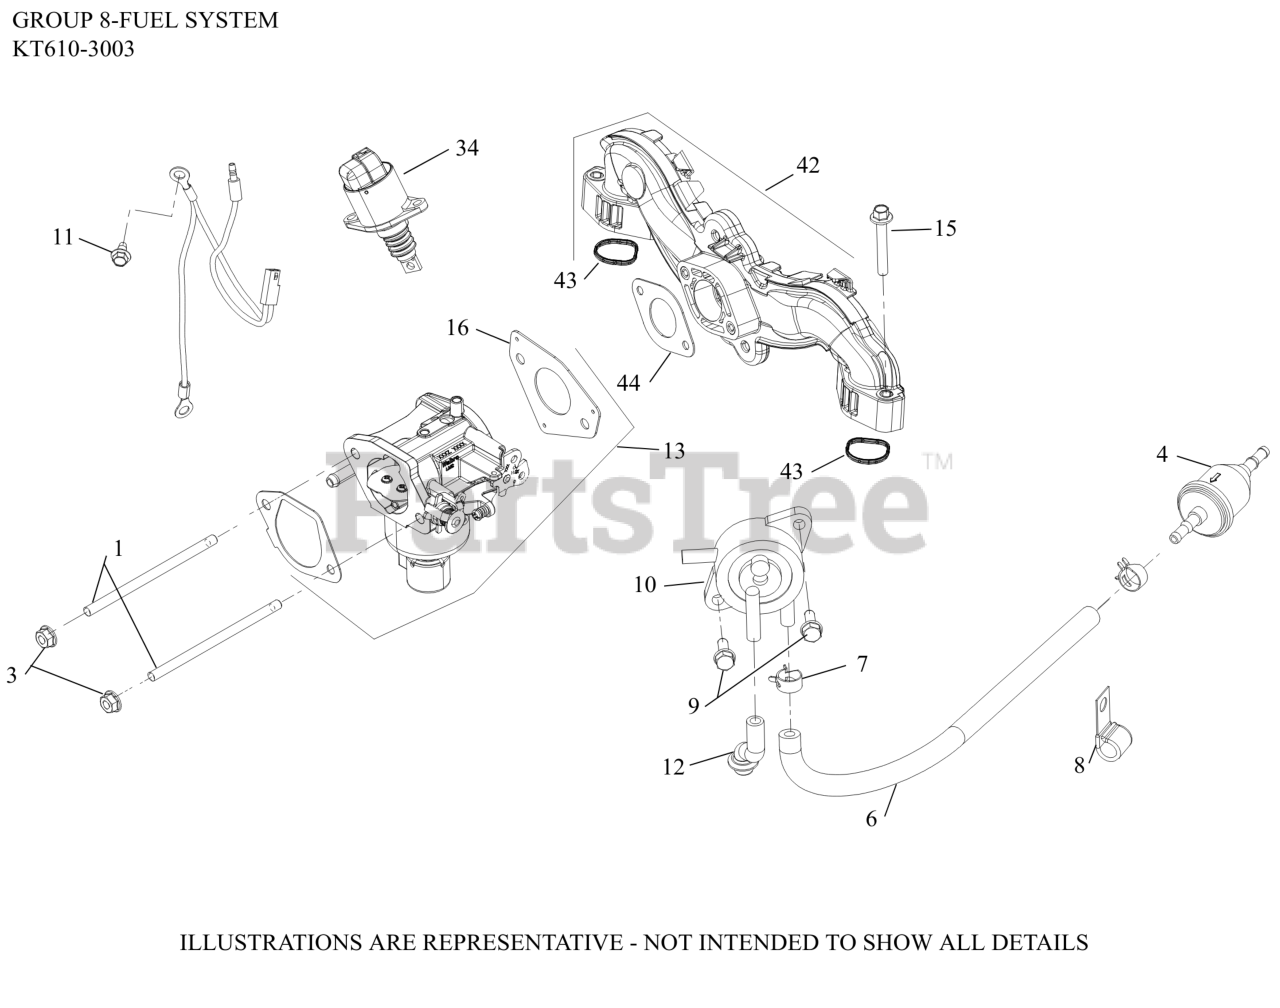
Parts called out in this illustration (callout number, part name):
3	NUT, FLG M6X1.0
4	FILTER,FUEL 51 MICRON (FUEL PUMP)
6	HOSE,LW PERM.FUEL 24.00"-USE 25 111 81-S
7	SPRING CLAMP, HOSE
8	CLIP, CABLE (KM)
9	SCREW, TAP M6X1.7X18
10	PUMP, FUEL (PULSE)-(#2539326S)
11	SCREW, THREAD FORMING
12	HOSE, PULSE PUMP(STEEL COVERS)
13	KIT,CARB(WALBRO)
15	SCREW, FLG M6X1.0X40
16	GASKET, CARBURETOR
34	ACTUATOR, LINEAR
42	INTAKE MANIFOLD W/GASKETS
43	O-RING, INTAKE PORT
44	GASKET, CARBURETOR (PIM, CV)
NI	KIT,REPAIR OVERHAUL(WALBRO)
NI	KIT,BOWL O-RING(WALBRO)
NI	KIT, HI ALTITUDE (5000 FT) 19MM
NI	KIT,SOLENOID REPAIR(WALBRO)
NI	KIT,REPAIR FLOAT(WALBRO)
